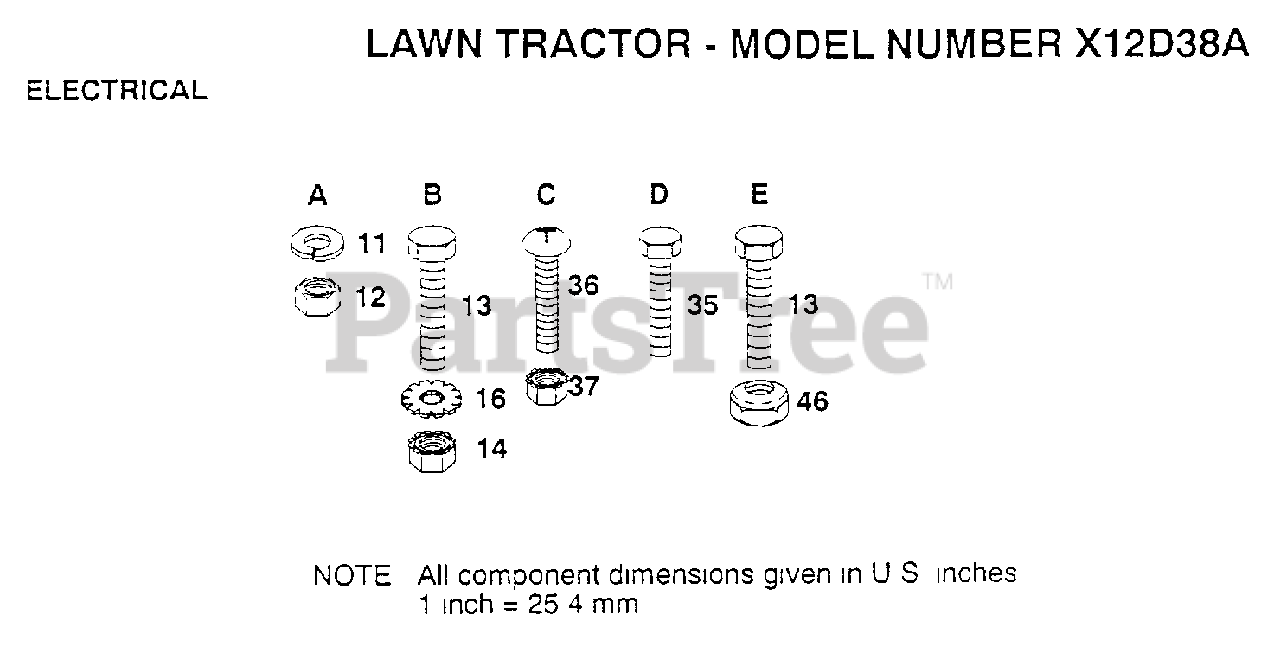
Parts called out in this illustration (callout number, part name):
12	NUT
13	BOLT
14	NUT
35	SCREW
37	"NUT,KEPS"
